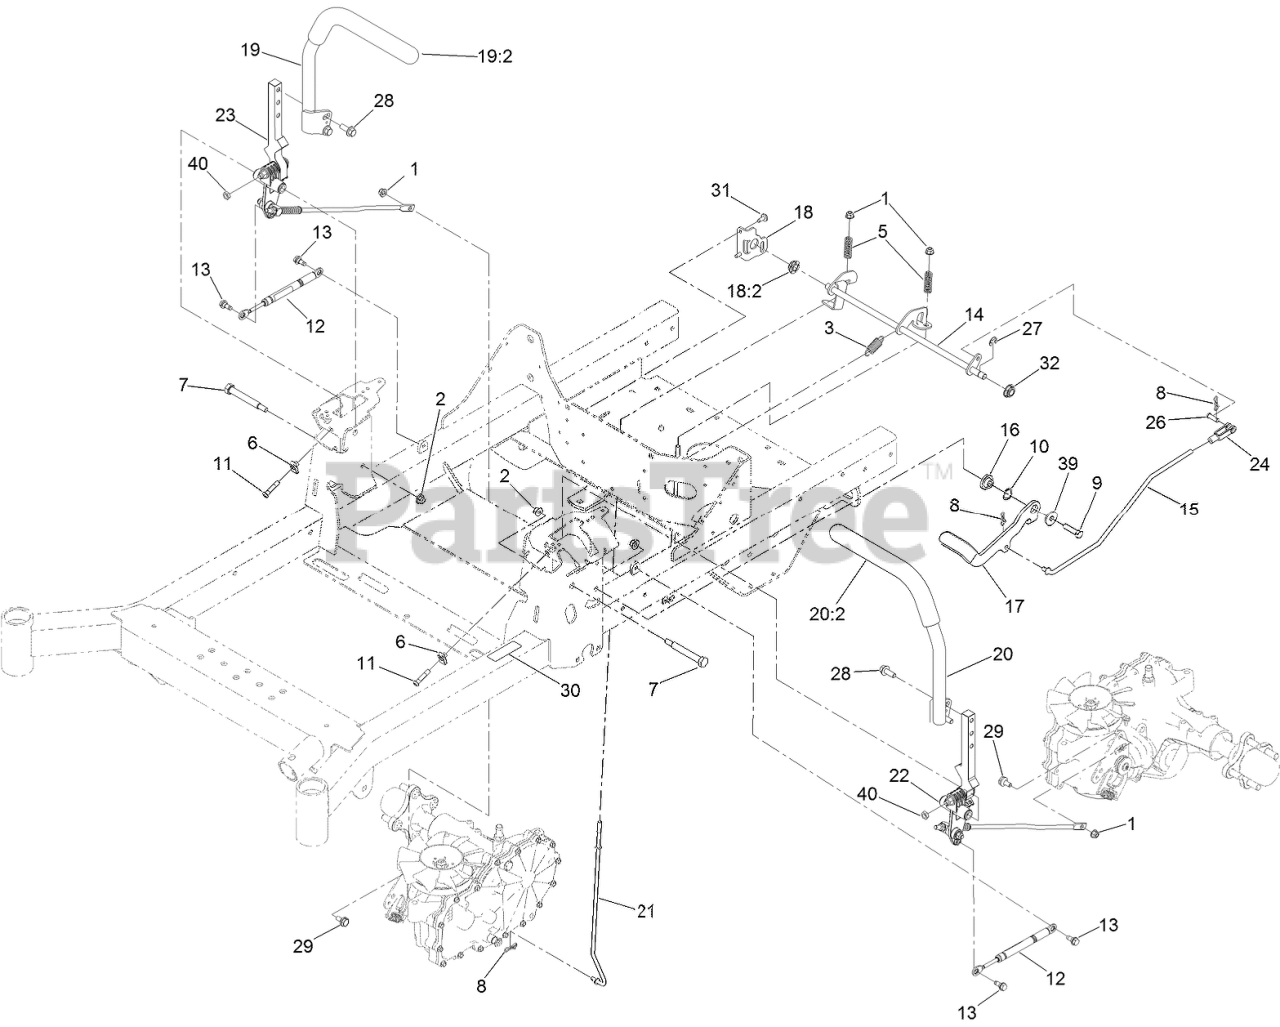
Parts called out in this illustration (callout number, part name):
1	NUT-HF, NI
2	NUT-HF, NI
3	SPRING-EXTENSION
5	SPRING-COMPRESSION
7	BOLT-PIVOT
8	PIN-COTTER, LOCKING
9	SCREW-HH
10	WASHER-WAVE
11	SCREW-HSBH
13	SCREW-SHOULDER
14	SHAFT-BRAKE
15	LINKAGE-BRAKE, UPPER
16	PIVOT-FLANGE
17	LEVER-BRAKE (WITH GRIP)
18	BRACKET-BRAKE
18:2	BEARING-SPHERICAL
19	RH CONTROL HANDLE ASM
20	LH CONTROL HANDLE ASM
21	LINKAGE-BRAKE, LOWER
22	Linkage-Brake, Lower
23	LH Motion Control ASM
24	YOKE-ADJUSTABLE
26	PIN-CLEVIS
27	RING-RETAINING, EXTERNAL
28	SCREW-HHF 3/8-16 X 1
29	BOLT-SHOULDER,HFH
30	DECAL-BRAKE, PARKING
31	SCREW-TORX
32	BEARING-SPHERICAL
39	WASHER
40	NUT-JAM
